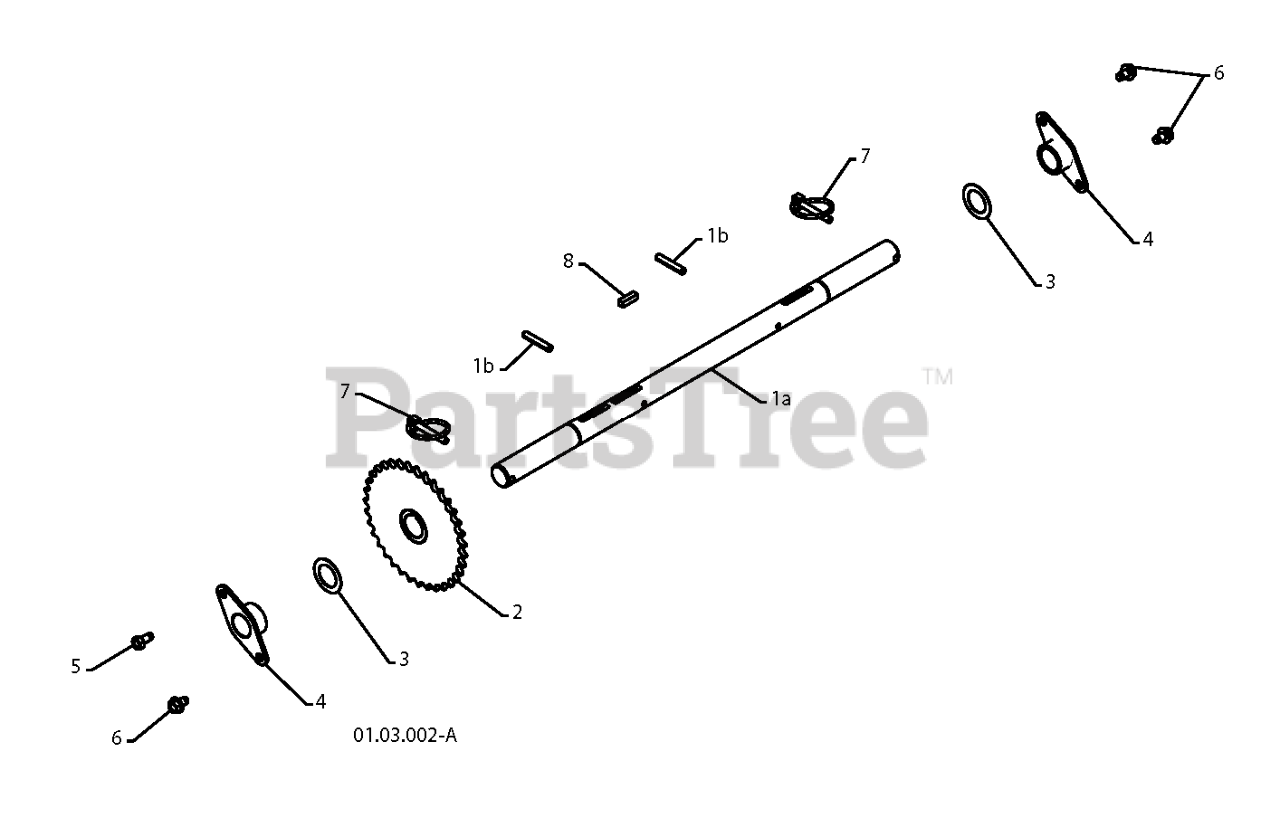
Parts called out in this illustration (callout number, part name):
1	AXLE.ASM.SHAFT.W/ROLLPIN.PS
2	SPROCKET.WELDMENT.AXLE.1.00
3	WASHER TRUST 1"
4	BEARING, AXLE
6	Screw 5/16-18 x 1/2 Hex, Self Tapping 5/16-18 x 1/2
7	PIN KLIK, 1/4
8	KEY, SQUARE 1/4 X .875
